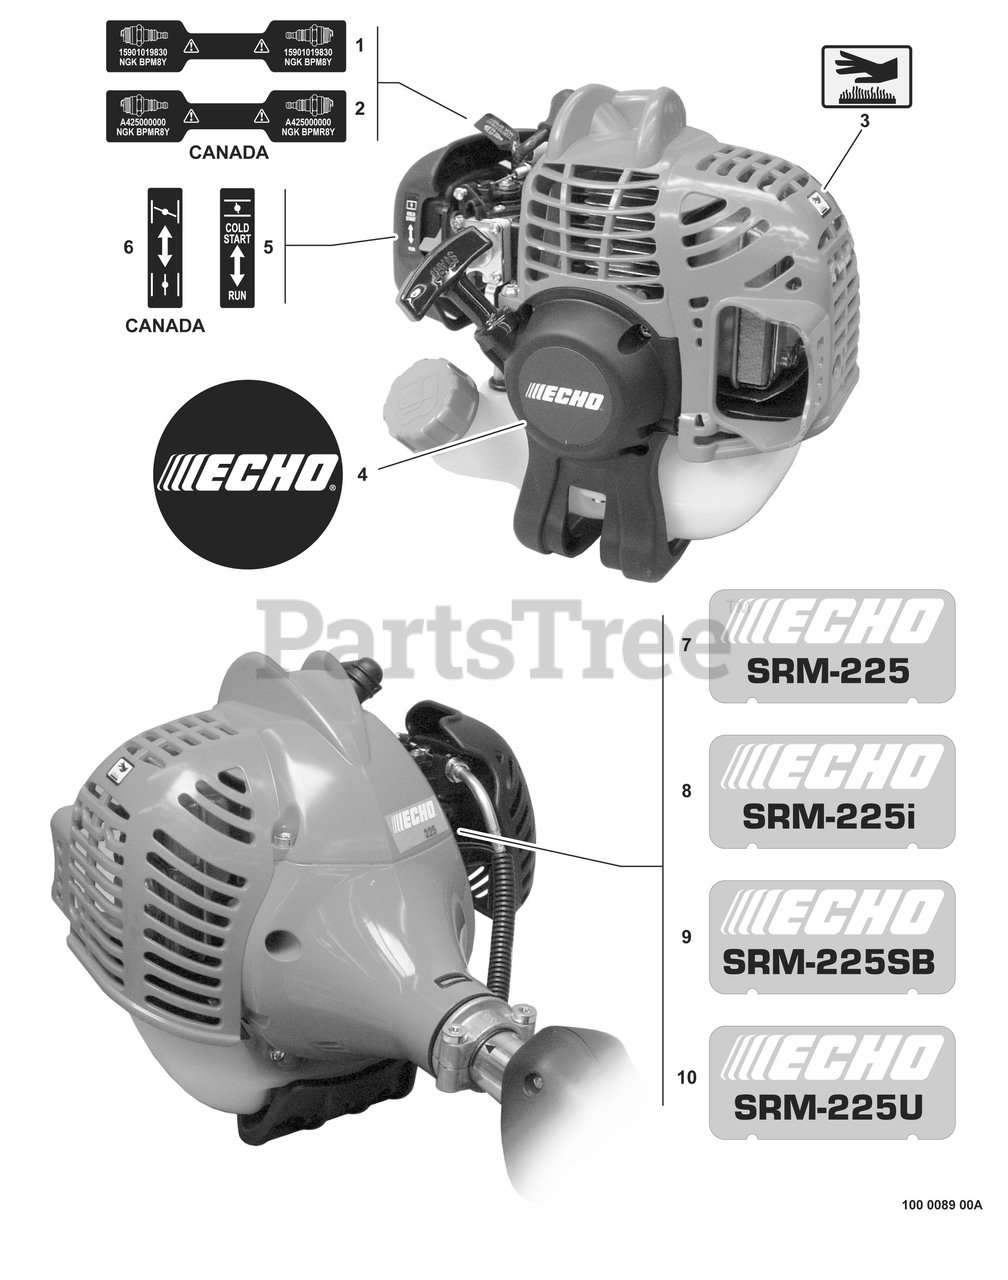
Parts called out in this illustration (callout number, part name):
1	LABEL - SPARK PLUG -- BPM-8Y
2	LABEL - SPARK PLUG -- BPMR-8Y
3	LABEL - HOT SURFACE
4	LABEL - ECHO
5	LABEL - CHOKE
6	LABEL - CHOKE
7	LABEL - MODEL SRM-225
8	LABEL - MODEL SRM-225i
9	LABEL - MODEL SRM-225SB
10	LABEL - MODEL SRM-225U
